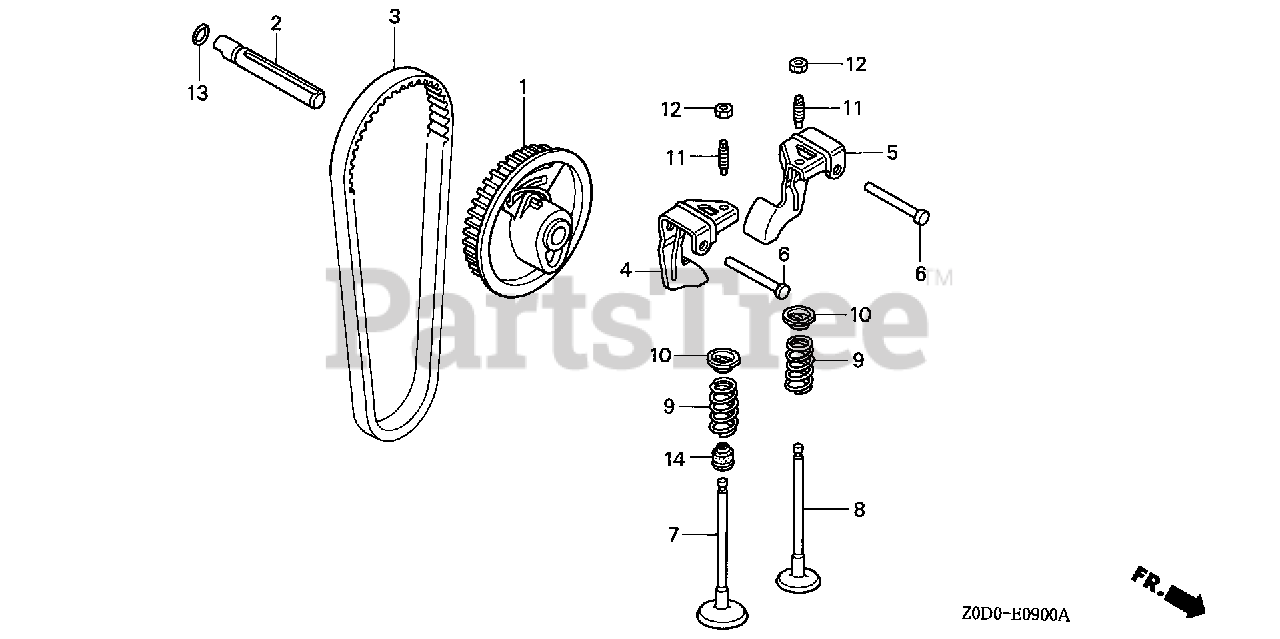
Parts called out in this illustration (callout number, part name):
1	PULLEY, CAMSHAFT
2	SHAFT, CAM PULLEY
3	BELT, TIMING (61YU7 G-200)
4	ARM, IN. VALVE ROCKER
5	ARM, EX. VALVE ROCKER
6	SHAFT, ROCKER ARM
7	VALVE, IN.
8	VALVE, EX.
9	SPRING, VALVE
10	RETAINER, VALVE SPRING
11	SCREW, TAPPET ADJUSTING
12	NUT, TAPPET ADJUSTING
13	O-RING (6.8X1.9) (ARAI)
14	SEAL, VALVE STEM
